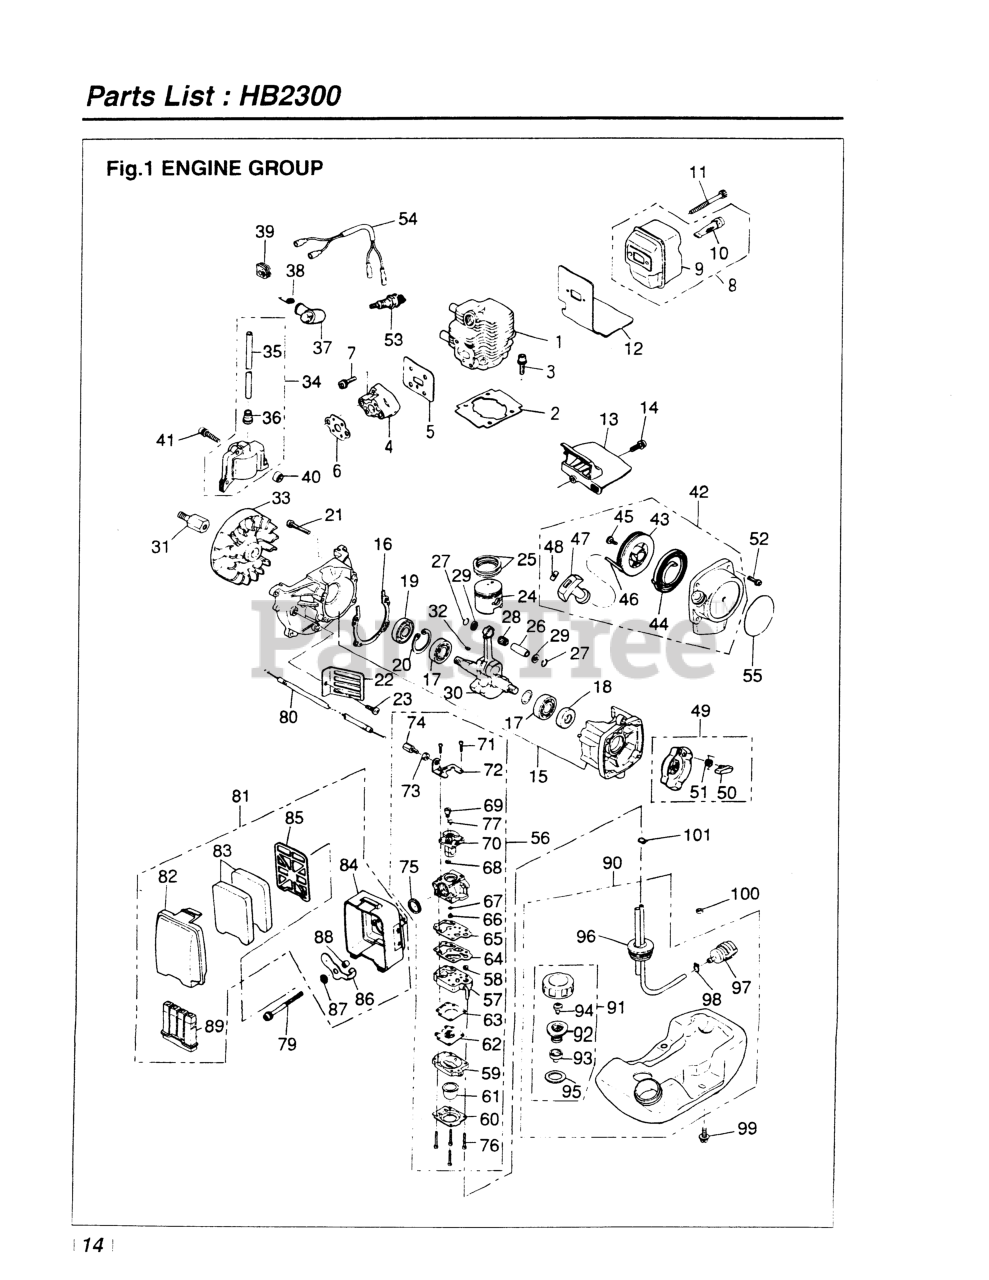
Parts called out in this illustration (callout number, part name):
1	CYLINDER
3	BOLT, M5 X 22
7	SCREW, M5X20 (RPLS.1400-75510)
10	ARRESTER (RPLS 5850-15140)
11	BOLT
12	GASKET
14	SCREW, M4 X 16
15	CRANKCASE
17	BEARING
18	SEAL, OIL (RPLS 1100-21210)
19	SEAL, OIL (RPLS 1140-21220)
20	RING, SNAP, M28 x 1.2
21	BOLT, M5 X 30
23	SCREW,M5 X 14 (RPLS 1400-15510
24	PISTON (REPLACES 1140-41110)
25	RING, PISTON (RPLS 1850-41210)
26	PIN, PISTON 5x8x26
27	RING, SNAP (RPLS 1101-41320)
29	WASHER
30	CRANKSHAFT (RPLS 1850-42000)
31	EXTENSION
32	KEY
33	ROTOR
34	COIL ASSY (RPLS 5500-71200)
35	CORD
36	CAP
38	SPRING
39	GROMMET
40	SPACER (RPLS -71260)
41	BOLT
42	RECOIL ASSEMBLY
43	REEL
44	SPRING, SPIRAL
45	SCREW (RPLS -75150)
47	KNOB
48	PLATE, STOPPER
49	PULLEY ASSY (RPLS -75210)
50	RATCHET (RPLS 1850-75220)
51	SPRING, RETURN
52	SCREW, M4 X 16
54	CORD COMPLETE
55	LABEL (USE -75611)
56	CARBURETOR
57	BODY, PUMP
59	BODY, PURGE
60	COVER, PUMP
61	PUMP, PRIMING
62	DIAPHRAGM (USE 4810-81260)
63	GASKET, DIAPHRAGM
64	DIAPHRAGM
65	GASKET, PUMP
66	JET
67	RING, O
68	RING
69	SWIVEL
70	VALVE ASSEMBLY
71	SCREW
73	NUT, CABLE ADJUSTER
74	SCREW, CABLE ADJUSTER
75	RING, PACKING
76	SCREW
77	WASHER
79	SCREW, M5 x 60
80	CABLE COMP (RPLS, -83100)
82	COVER
83	FILTER
84	HOUSING
85	PLATE
86	VALVE, CHOKE
87	WASHER
88	SLEEVE (REPLACES 1750-82060)
89	SILENCER
93	HOLDER, CAP
94	VALVE (NLA WHEN OUT)
95	PACKING
96	PIPE COMP.
97	FILTER (RPLS 1850-85300)
98	CLIP (REPLACES 2841-31280)
99	SCREW (REPLACES 4500-13180)
100	COLLAR (REPLACES -85530)
101	CLIP
